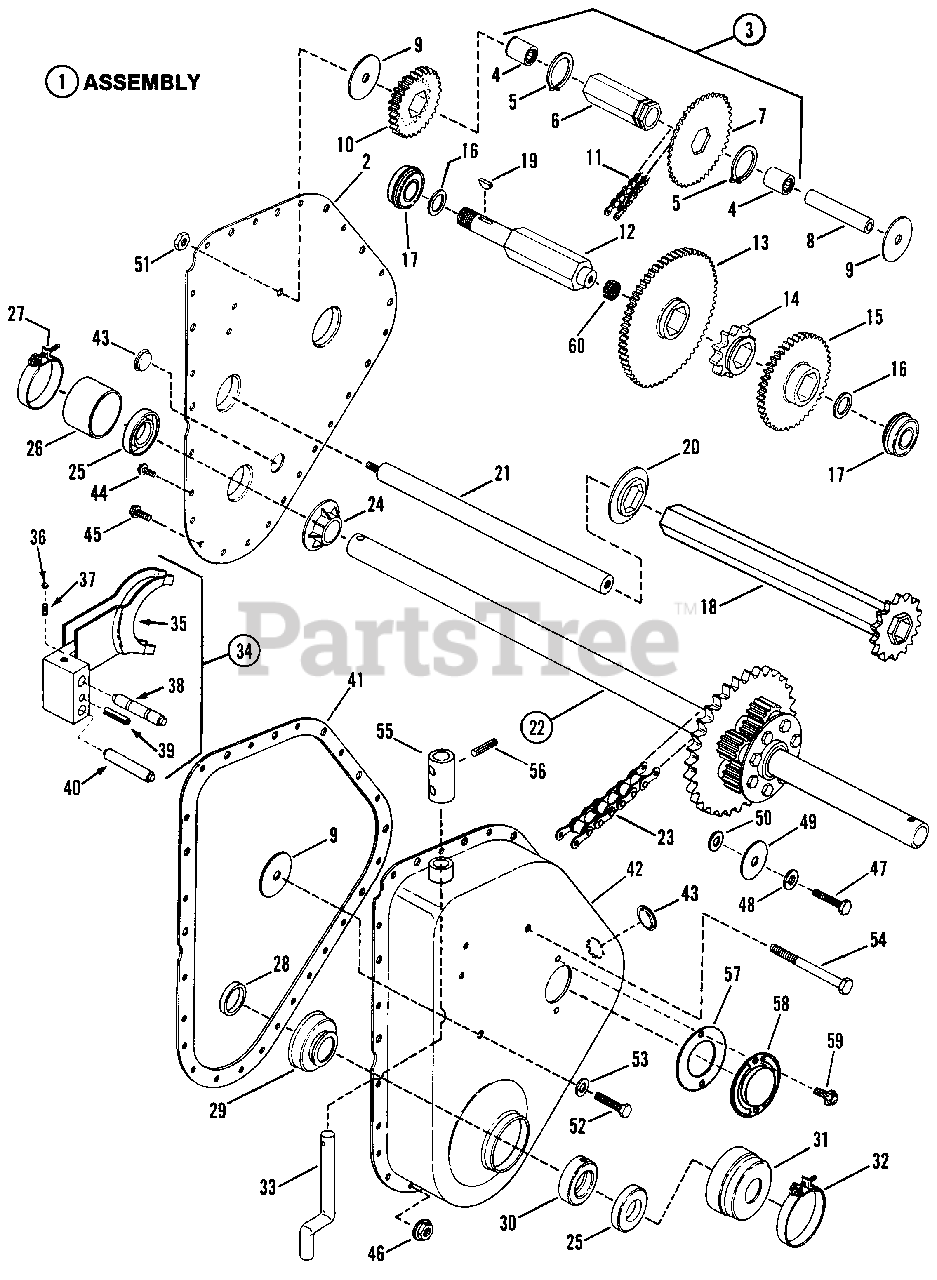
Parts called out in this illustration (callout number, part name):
1	ASSEMBLY, TRANSMISSION
2	COVER, Transmission
3	ASSEMBLY, Hex Tube (Short)
4	BEARING, Needle
5	RING, Retaining
6	TUBE, Hex
7	SPROCKET, 46 Tooth (#35)
8	RACE, Bearing
9	THRUST WASHER
10	CLUSTER GEAR
11	CHAIN, 56 Pitch (#35)
12	SHAFT, Third Reduction (4.777" Long)(1984)
12	SHAFT, Third Reduction (6.027" Long)(1985)
13	GEAR, 67 Tooth, 12 Pitch
14	SPROCKET, 10 Tooth (#50)
15	GEAR, 47 Tooth, 12 Pitch
16	SHIM WASHER
17	BEARING
18	ASSEMBLY, Drive Hex Tube
19	KEY, Woodruff (#9)
20	SPECIAL WASHER (Hex Insert)
21	SHAFT, Drive Tube Support
22	DIFFERENTIAL (NLA)
23	CHAIN, 42 Pitch (#50)
24	SPECIAL WASHER
25	OIL SEAL
26	CAP, Seal
27	CLAMP, 1-7/8" Hose
28	SPACER, Bearing
29	BEARING, Ball
30	COLLAR, Lock
31	CAP, Dust Seal
32	CLAMP, For 2.69" Hose
33	ROD, (HI-LO Range) Shift
34	ASSEMBLY, HI-LO Shifter
35	FORK, Shift
36	BALL, Detent
37	SPRING, Detent Ball
38	GUIDE-PIN, Detent
39	ROLL-PIN, 1/4 x 1-1/4"
40	GUIDE-PIN, Shift
41	GASKET, Cover to Case
42	ASSEMBLY, Transmission Case
43	PLUG, Oil Fill & Check
44	SCREW, 1/4-20 x 5/8" HWF Self Tap
45	BOLT, 1/4-20 x 1/2" HWF (2-Locating)
46	NUT, 1/4-20 Hex Flange Lock
47	SCREW, 5/16-24 X 3/4" Hex Head Cap
48	WASHER, 5/16 Split Lock
49	WASHER, 5/16" x 1-1/4" x 3/32" Flat
50	WASHER, 5/16 SAE
51	NUT, 3/8-16 Hex Top Lock
52	SCREW, 3/8-16 x 3/4" Hex Head Cap, Grade 5
53	WASHER, 3/8 Split Lock
54	SCREW, 3/8-16 x 3-1/4" Hex Head Cap
55	COUPLING, Shift Lever
56	ROLL-PIN, 3/16 X 3/4"
58	COVER, Bearing
59	SCREW, 1/4-20 x 3/8" Hex Washer Self-Tap
60	RING, 5/8 Tolerance
